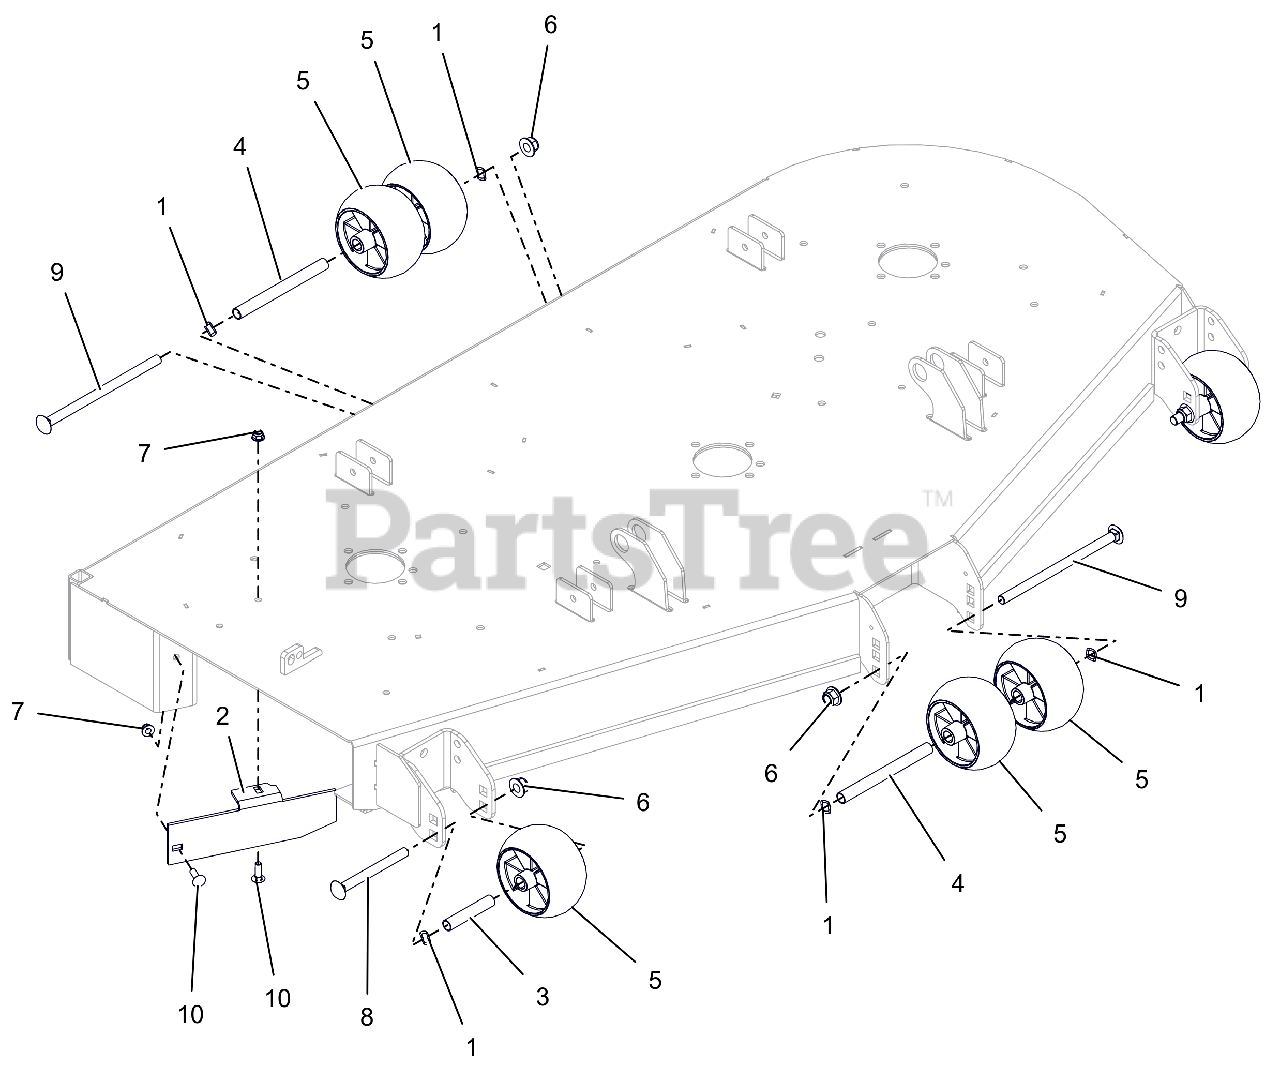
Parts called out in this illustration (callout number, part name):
1	WAVE WASHER .531X.781X.125FH
2	60" DISCHARGE BAFFLE - RED
3	SPACER, .510X.625X3.35
4	SPACER, .510X.625X6.50
5	ANTI-SCALP WHEEL - 5X3 CTR
6	NUT,NYL-FLG .50-13 GF ZCC
7	NUT,NYL-FLG .31-18 GF ZCC
8	BLT, RHSN .50-13X5.00 G5 ZCC
9	BLT, RHSN .50-13X8.50 G5 ZCC
10	BLT,RHSN .31-18X1.00 G5 ZCC
